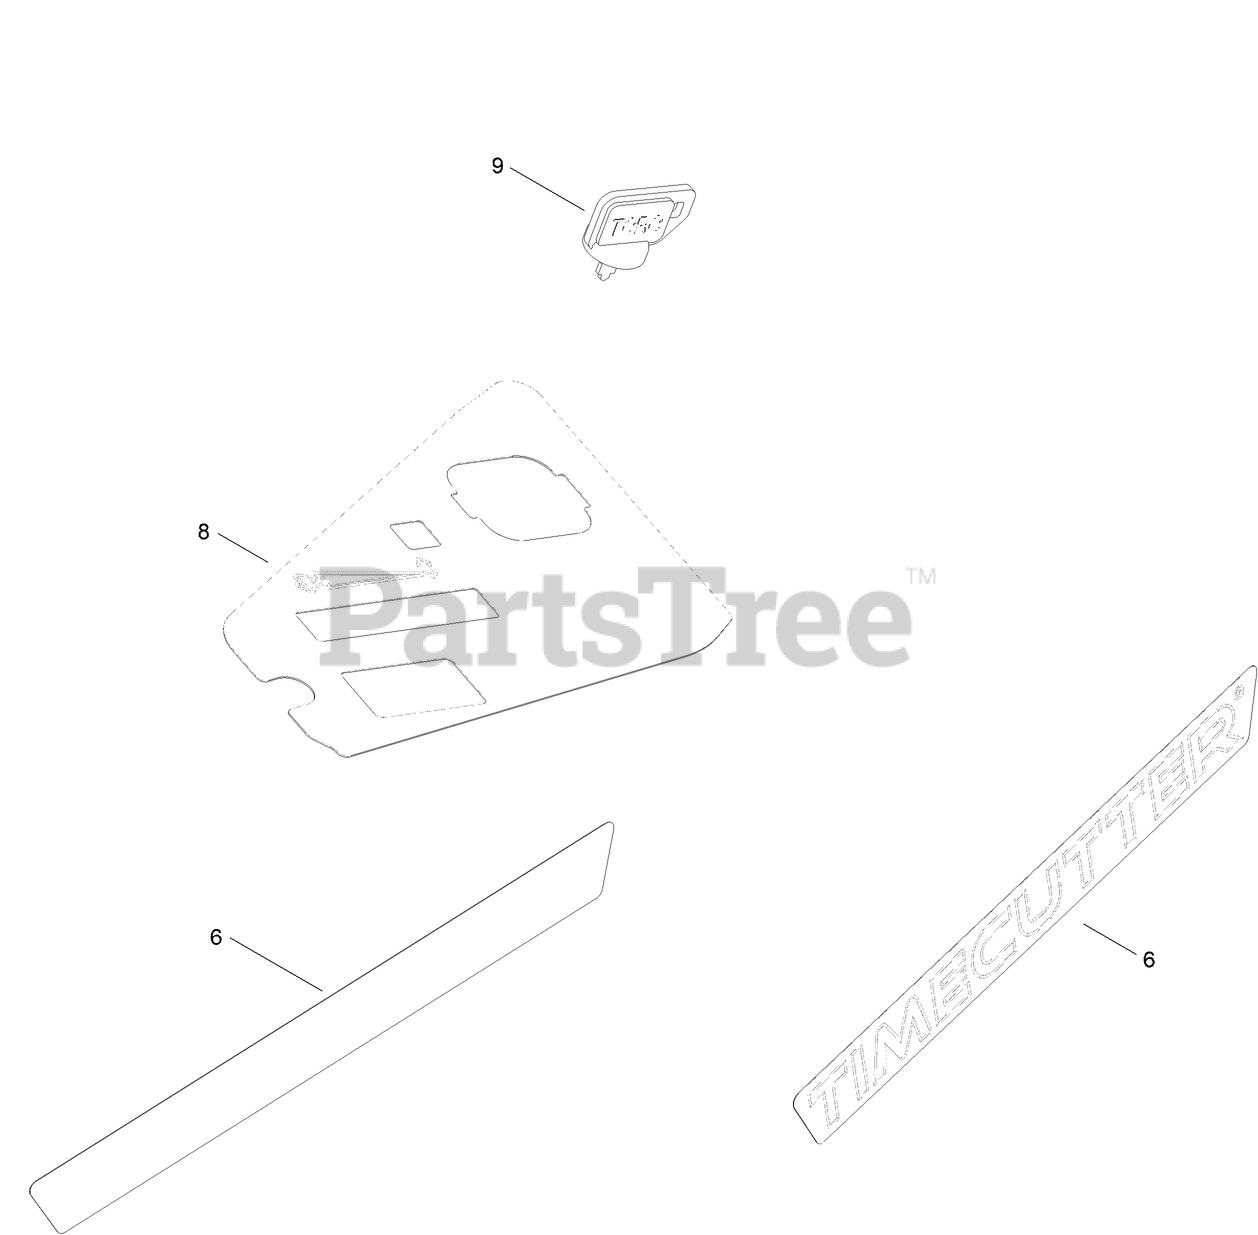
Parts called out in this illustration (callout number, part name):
6	DECAL-TIMECUTTER
8	DECAL - CONTROL PANEL W/OUT HOUR METER
9	KEY-IGNITION
